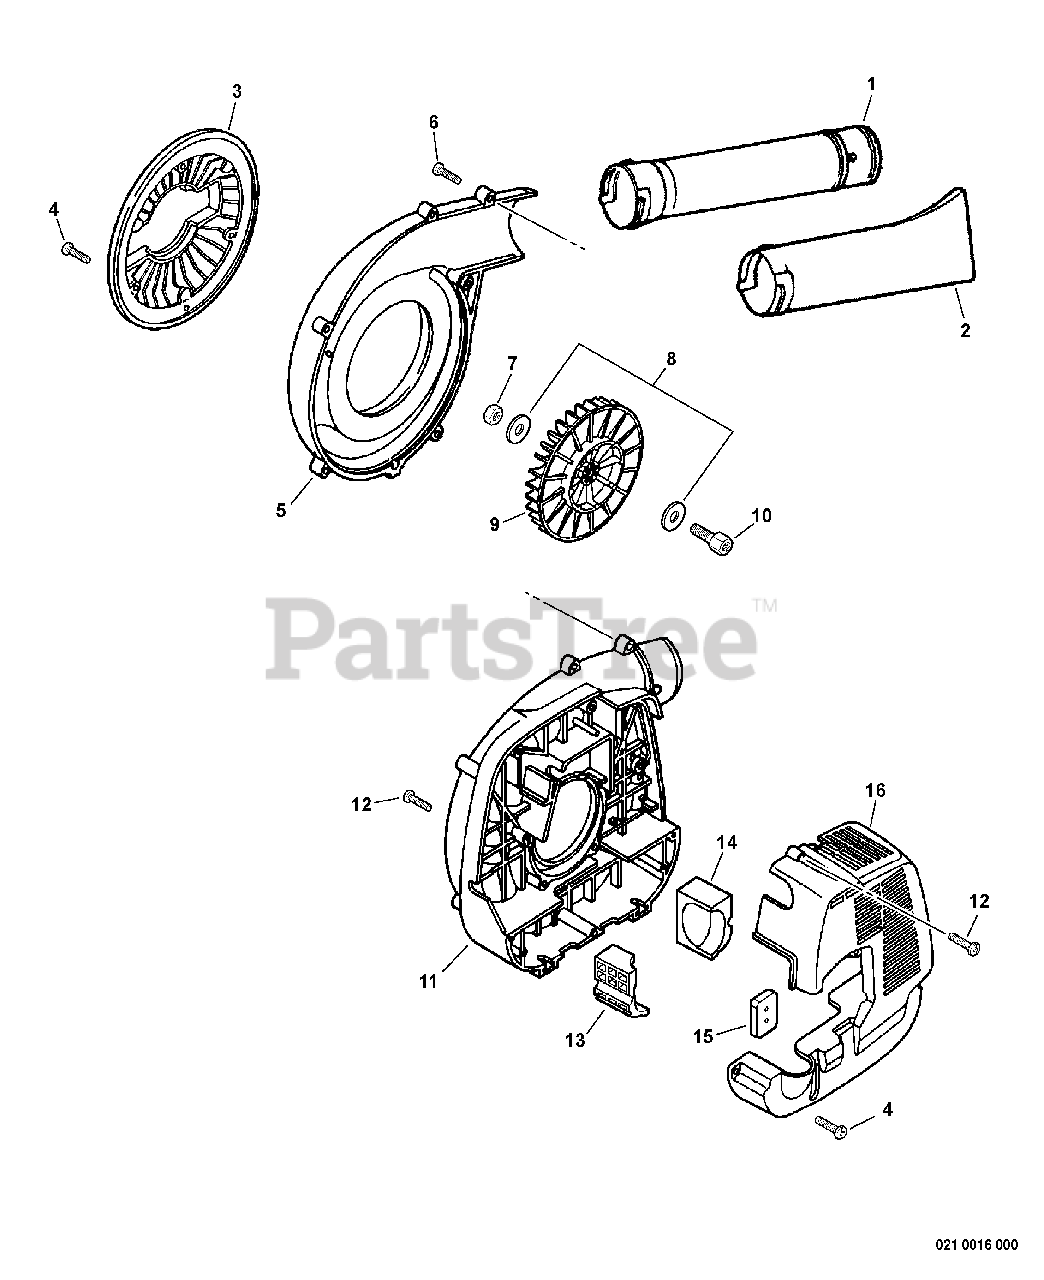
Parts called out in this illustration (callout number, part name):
1	TUBE, BLOWER - STRAIGHT
2	TUBE, BLOWER
3	SHIELD, DEBRIS
4	SCREW 5×16
5	COVER, FAN - OUTER
6	SCREW, TAPPING 5×20
10	HUB, FAN
11	COVER, FAN - INNER
12	BOLT 5×20
13	CUSHION
14	CUSHION
15	CUSHION
16	COVER, ENGINE
